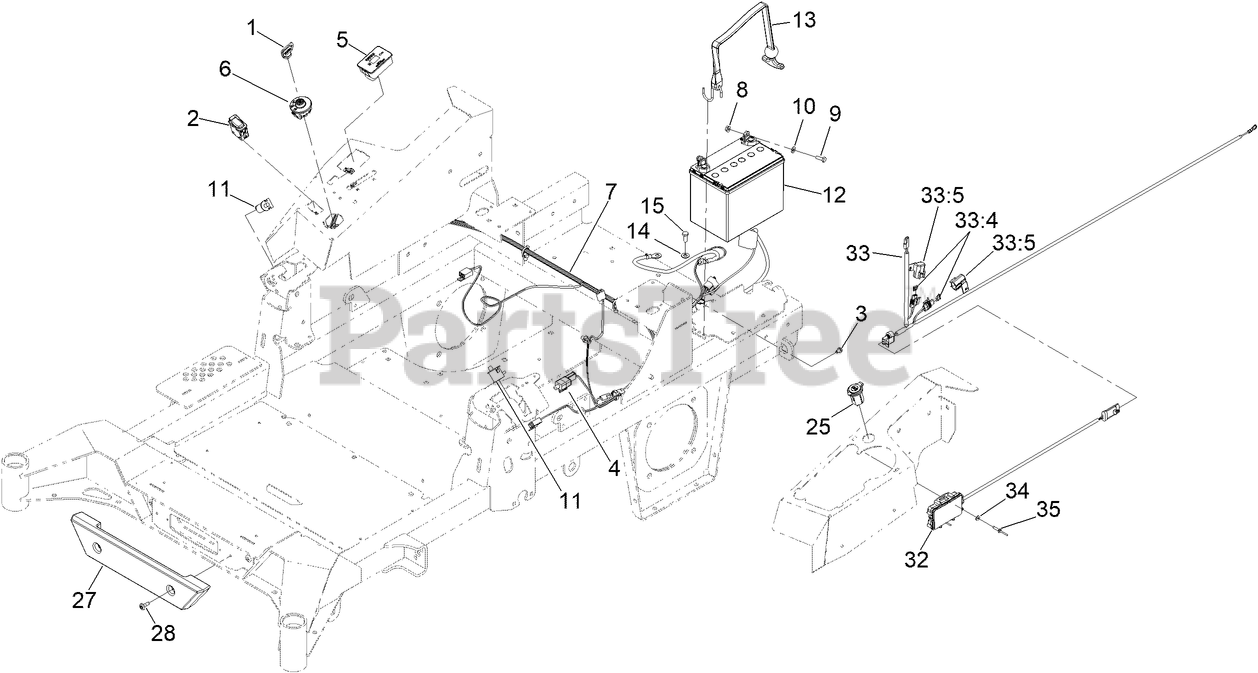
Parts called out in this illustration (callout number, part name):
1	KEYS-IGNITION (SPARE PAIR)
1	KEY-IGNITION
2	SWITCH-ROCKER, ON-NONE-ON
3	SCREW-HWH
4	SWITCH
5	MODULE ASM
6	SWITCH-IGNITION
7	HARNESS-WIRE
8	NUT-HF
9	SCREW-HH
10	WASHER-FLAT
11	SWITCH-BAIL
12	BATTERY-DRY
13	STRAP, BUNGEE
14	WASHER-PLAIN
15	SCREW-HH
25	PORT-POWER, USB
27	BUMPER-FRONT
28	SCREW-SHOULDER
32	GPS ASM
33	HARNESS-WIRE, GPS
33:4	FUSE-MINI BLADE, 5 AMP
33:5	COVER-FUSE, SINGLE
34	WASHER-PLAIN
35	RIVET-POP
